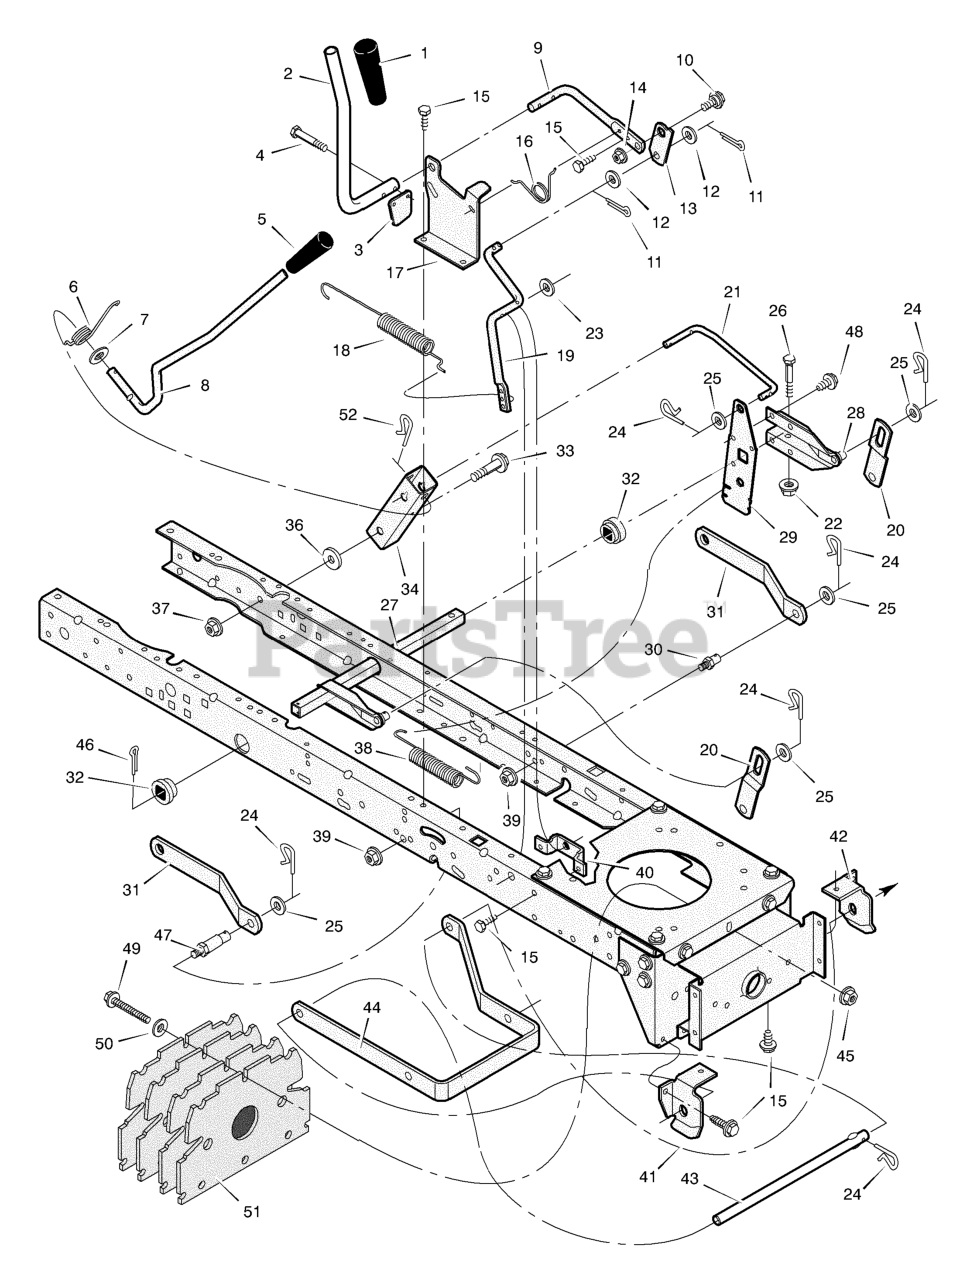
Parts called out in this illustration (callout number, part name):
1	Grip
2	Handle, PTO
3	Pad, Switch
4	Screw, Hex
5	Grip
8	Handle, Lift
9	Lever, PTO
10	Bolt, Shoulder
11	Pin, Cotter
13	Link, PTO
14	Nut, Flange
17	Bracket, PTO
18	Spring, PTO
19	Crank, PTO
20	Link, Lift
21	Link, Lift Handle
22	Nut, Flange
24	Pin, Hair
26	Bolt, Hex
27	Arm Assembly, Right Lift
28	Arm, Right Lift
29	Plate, Lift Arm
30	Pin
31	Bracket, Rear Suspension
32	Bushing, Lift Tube
33	Bolt, Shoulder
34	Bracket, Pivot
37	Nut, Flange
39	Nut, Flange
40	Bracket, PTO
41	Hanger, Right Deck
42	Hanger, Left Deck
43	Rod, Hanger
44	Hanger, Front
45	Nut, Flange
46	Pin, Cotter
47	Pin, Threaded Shoulder
49	Bolt, Hex
51	Plate, Weight (4 Required)
52	Pin, Hair
